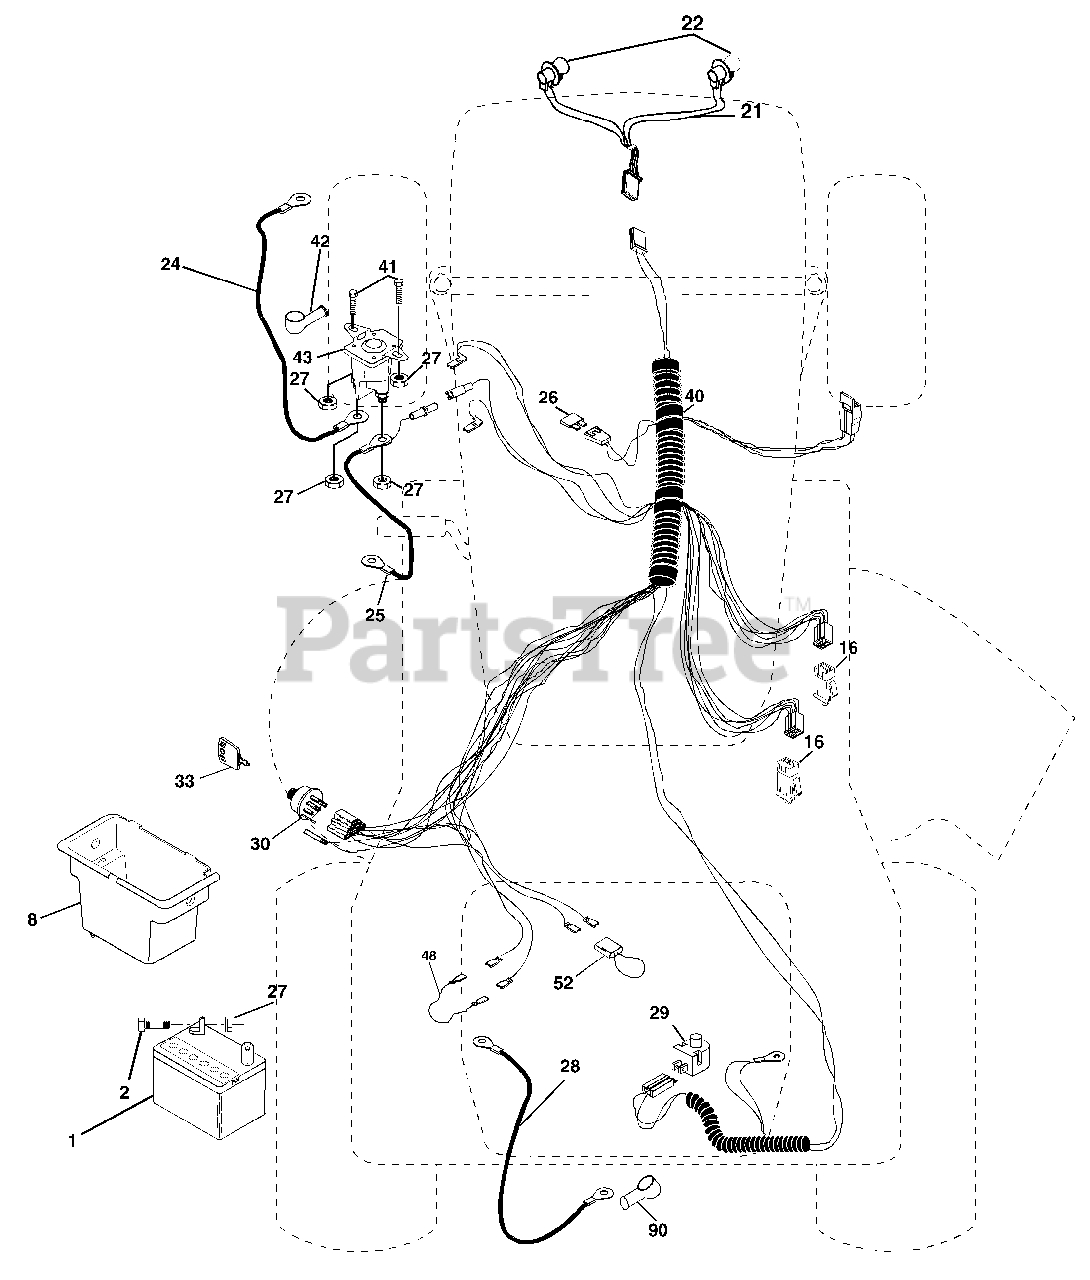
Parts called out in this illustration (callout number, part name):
1	Battery 12 Volt 25 Amp
2	Bolt Hex Hd 1/4-20unc X 3/4
8	Box Battery
16	Switch Interlock Push -In
21	Harness Asm Light W/4152J
22	Bulb Light #1156
24	Cable Battery 6 Ga 11" red
25	Cable Battery 6 Ga w/16 wire, red
26	Fuse 20 AMP
27	Nut Keps Hex 1/4-20 unc
28	Cable Ground 6 Ga 12" black
29	Switch Plunger Nc Gray
30	Switch Ign
33	Key Ign
40	Harness Ign
41	Bolt Blk Fin Hex 1/4-20 X 1/2
42	Cover Terminal Red
43	Solenoid
48	Adapter Ammeter
52	Protection Wire Loop
90	Cover Terminal
